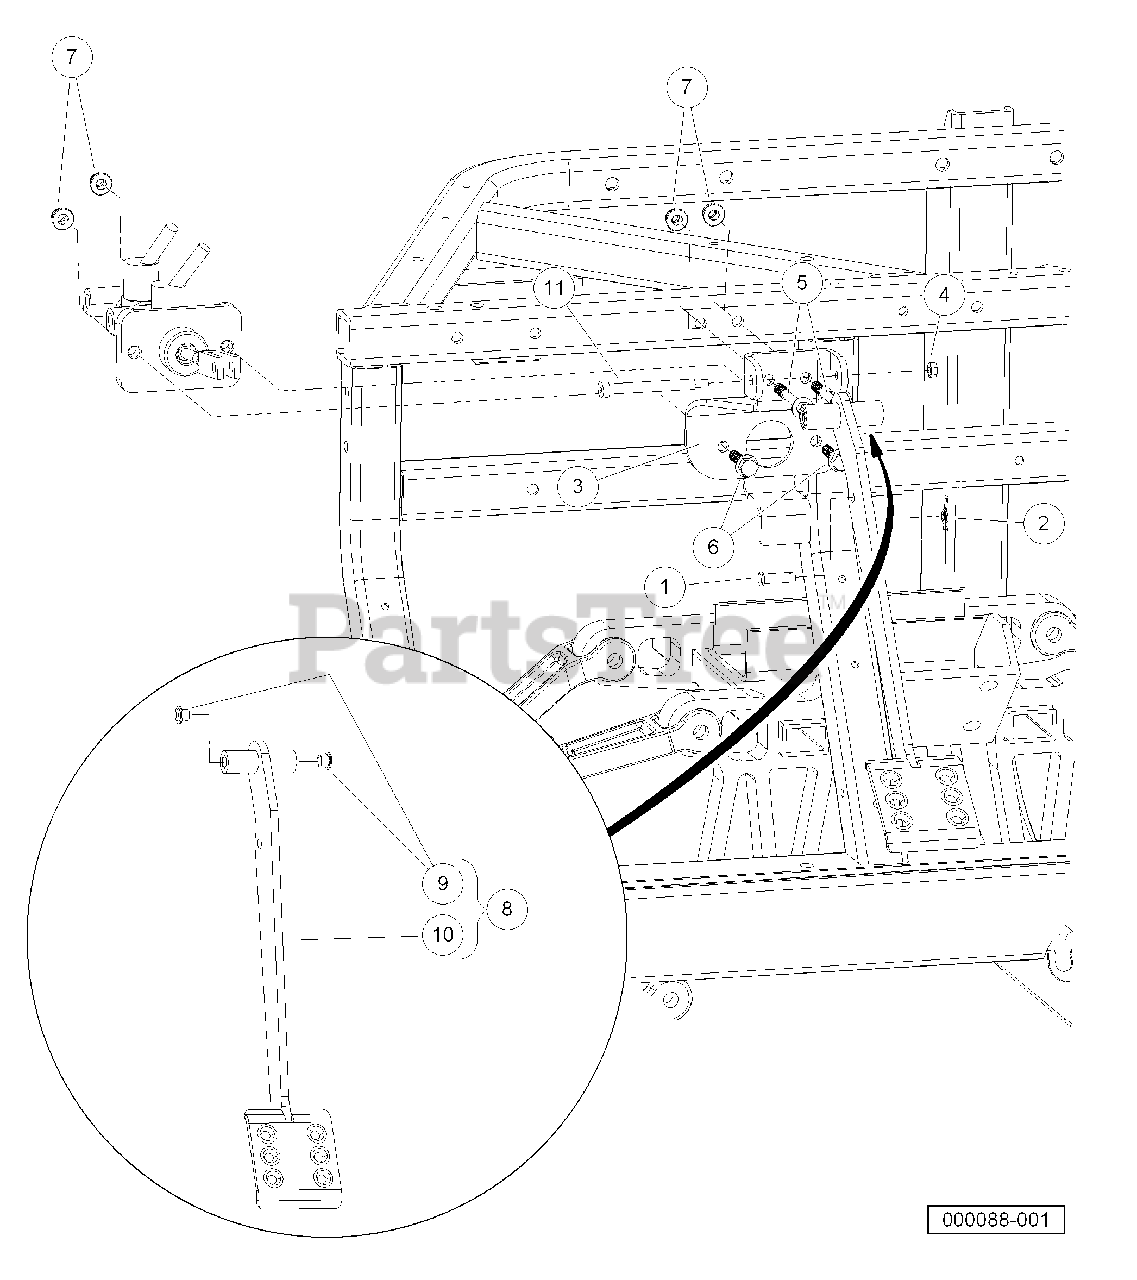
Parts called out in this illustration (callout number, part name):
1	Clevis Pin, 5/16 X 1
3	Bracket, Pedal, Brake
4	Nut M6x1 Mech Def Center
5	Bolt Flanged Head, M8 X 1.25 X 65
6	Bolt Flanged Head, M8 X 1.25 X 35
7	Lock Nut, Flg M8 X 1.25 Nylon
8	Asm, Pedal, Brake, Hung
9	Bushing, Greaseless
10	Weldment, Pedal, Brake, Hung
11	Bolt, Shoulder, M8 X 70, Hc
